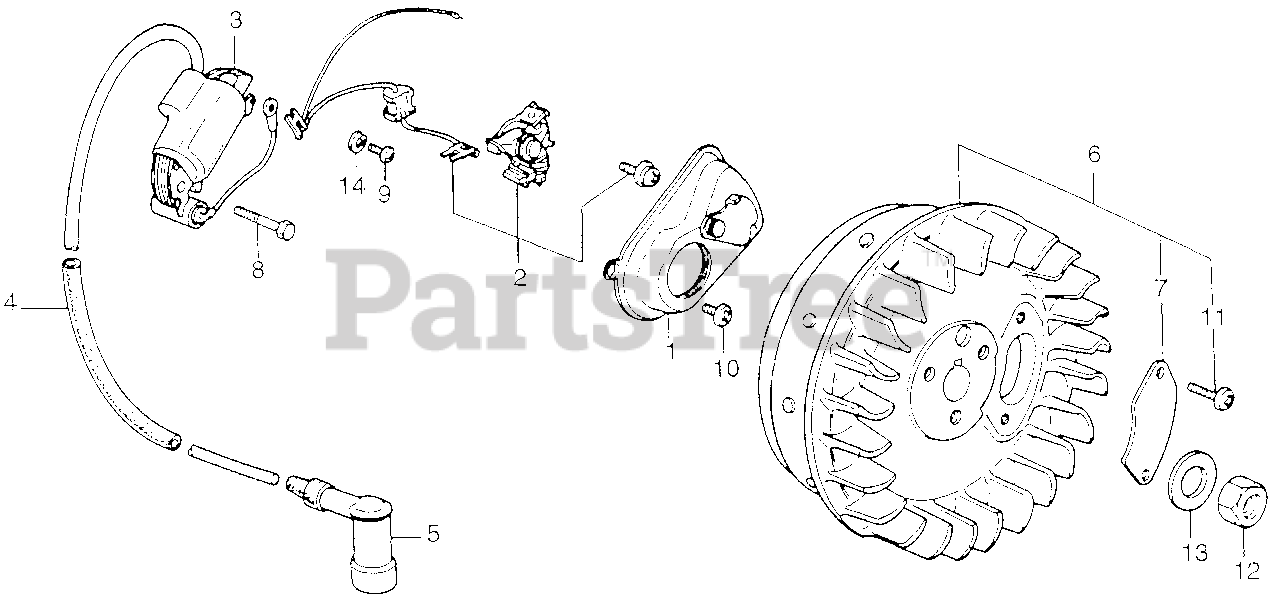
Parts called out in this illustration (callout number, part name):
1	COVER, POINT
2	POINTS ASSY.
3	COIL, IGNITION (KOKUSAN)
4	TUBE, IGNITION RUBBER (NOT AVAILABLE)
5	CAP ASSY., NOISE SUPPRESSOR
6	MAGNETO, FLYWHEEL (KOKUSAN) (NOT AVAILABLE)
7	COVER, FLYWHEEL WINDOW (NOT AVAILABLE)
8	BOLT, HEX. (6X28)
9	SCREW, PAN (3X7) (SOURCE: VINTAGE PARTS INC.)
10	SCREW, PAN (5X6)
11	SCREW, PAN (5X8)
13	WASHER (14MM)
14	WASHER, SPRING (3MM)
